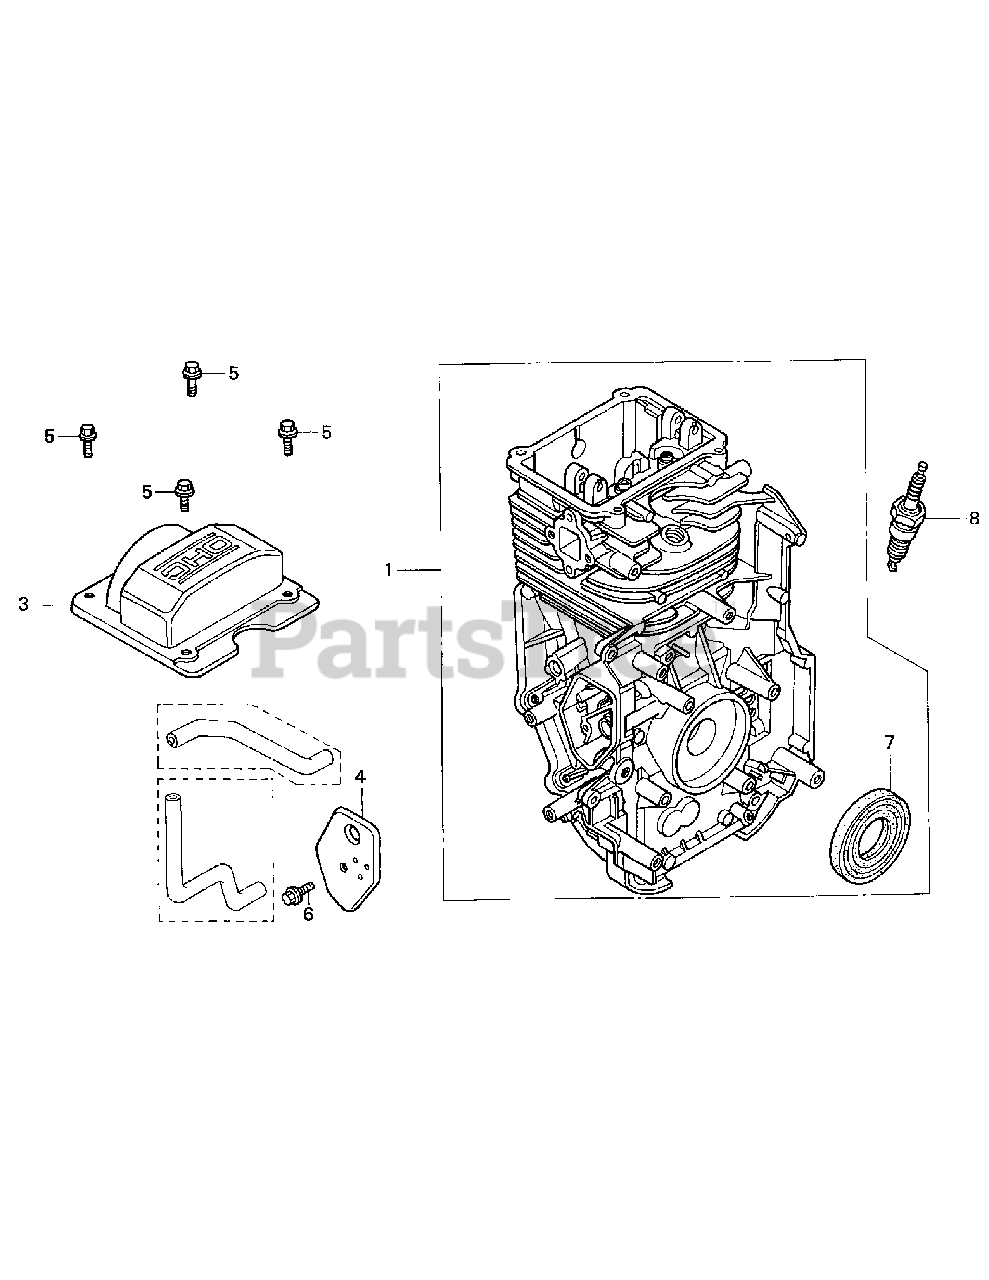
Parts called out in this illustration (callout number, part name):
1	CYLINDER ASSY. (010)
3	COVER, HEAD
4	COVER, BREATHER (BREATHER VALVE ASSY.)
5	BOLT, FLANGE (6X12) (CT200)
6	BOLT, FLANGE (6X14)
7	OIL SEAL (25.4X62X6)
8	SPARK PLUG (BPR6ES) (NGK)
